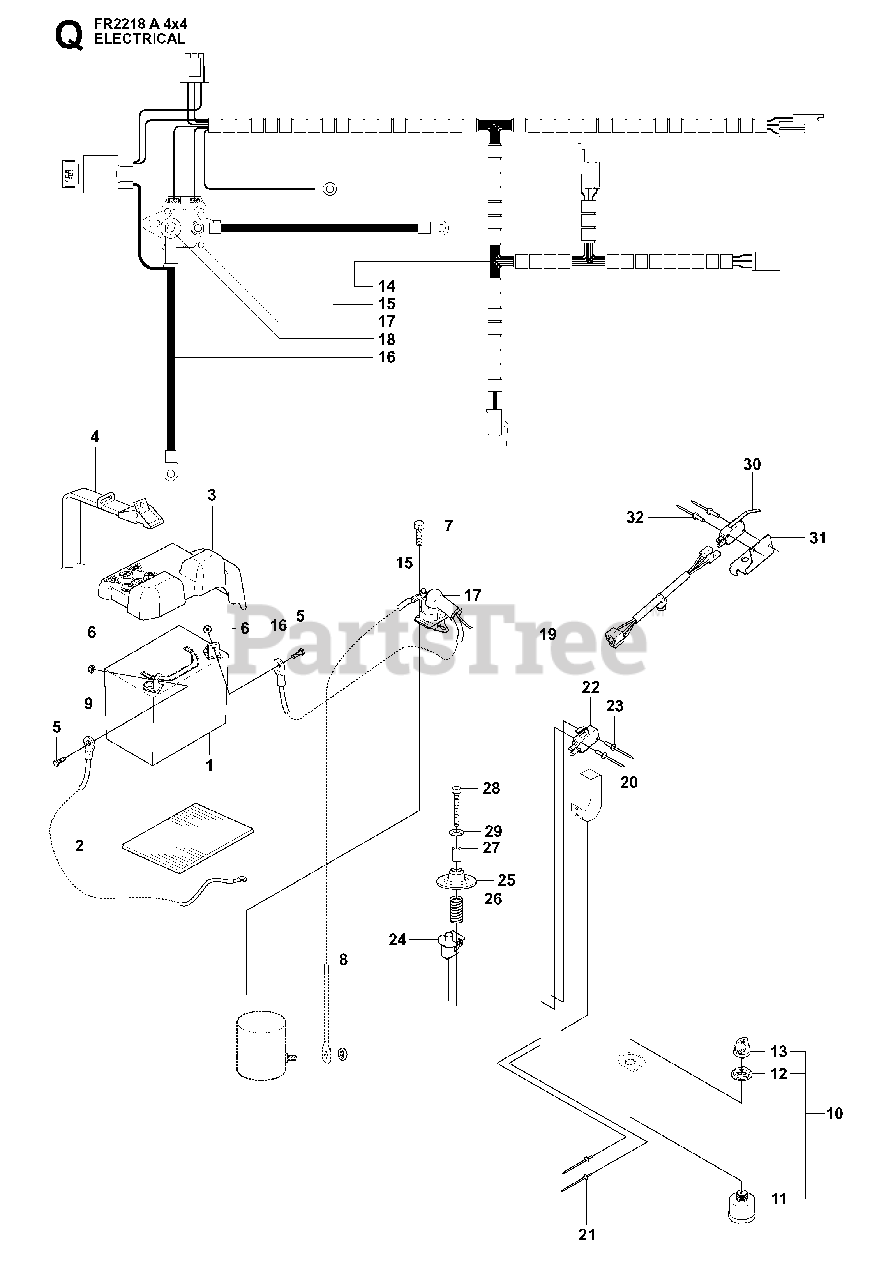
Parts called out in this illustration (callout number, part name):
10	IGNITION SWITCH
11	IGNITION SWITCH
13	IGNITION KEY
22	%BRAKER
27	SPACER TUBE
28	SCREW
29	WASHER BRB 8.4X17
30	RP MICRO SWITCH
